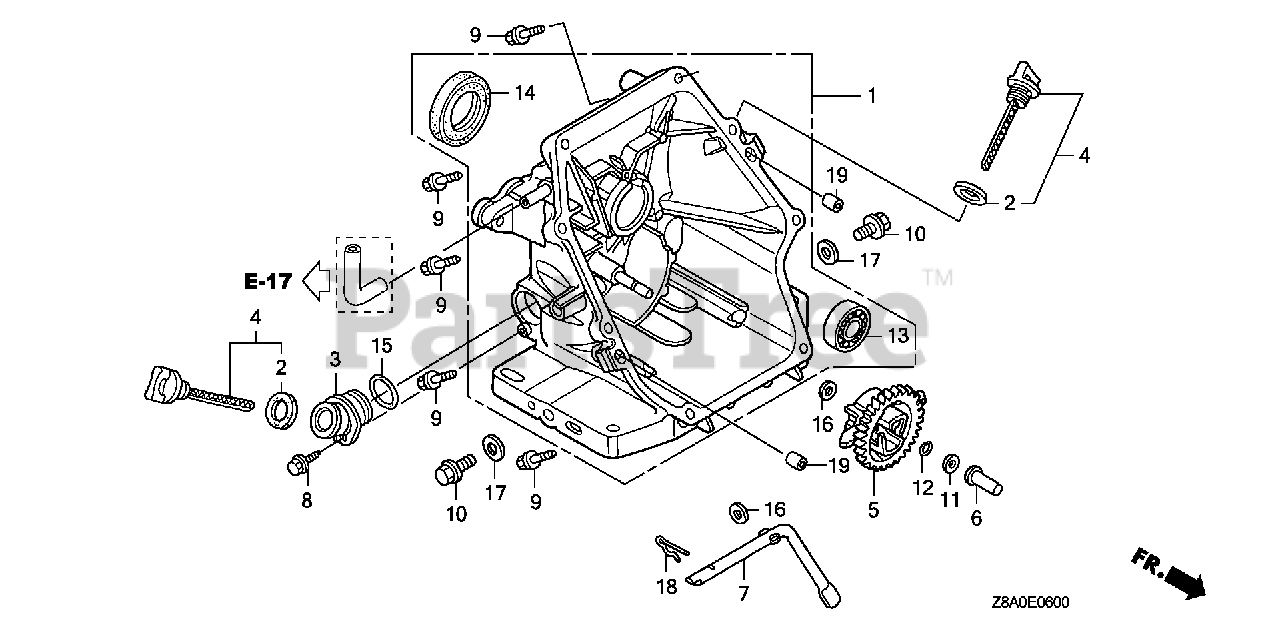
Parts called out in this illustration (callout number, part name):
1	COVER ASSY., CRANKCASE
2	GASKET, OIL FILLER CAP (NOT AVAILABLE)
4	GAUGE ASSY., OIL LEVEL
5	GOVERNOR ASSY.
6	SLIDER, GOVERNOR
7	SHAFT, GOVERNOR ARM
9	BOLT, FLANGE (6X25) Use up to Engine SN 2056819.
10	BOLT, DRAIN PLUG
11	WASHER, THRUST (6MM)
12	CLIP, GOVERNOR HOLDER
14	OIL SEAL (28X41.25X6)
16	WASHER, PLAIN (6MM)
17	WASHER, DRAIN PLUG (12MM)
18	PIN, LOCK (8MM)
19	PIN, DOWEL (8X20)
